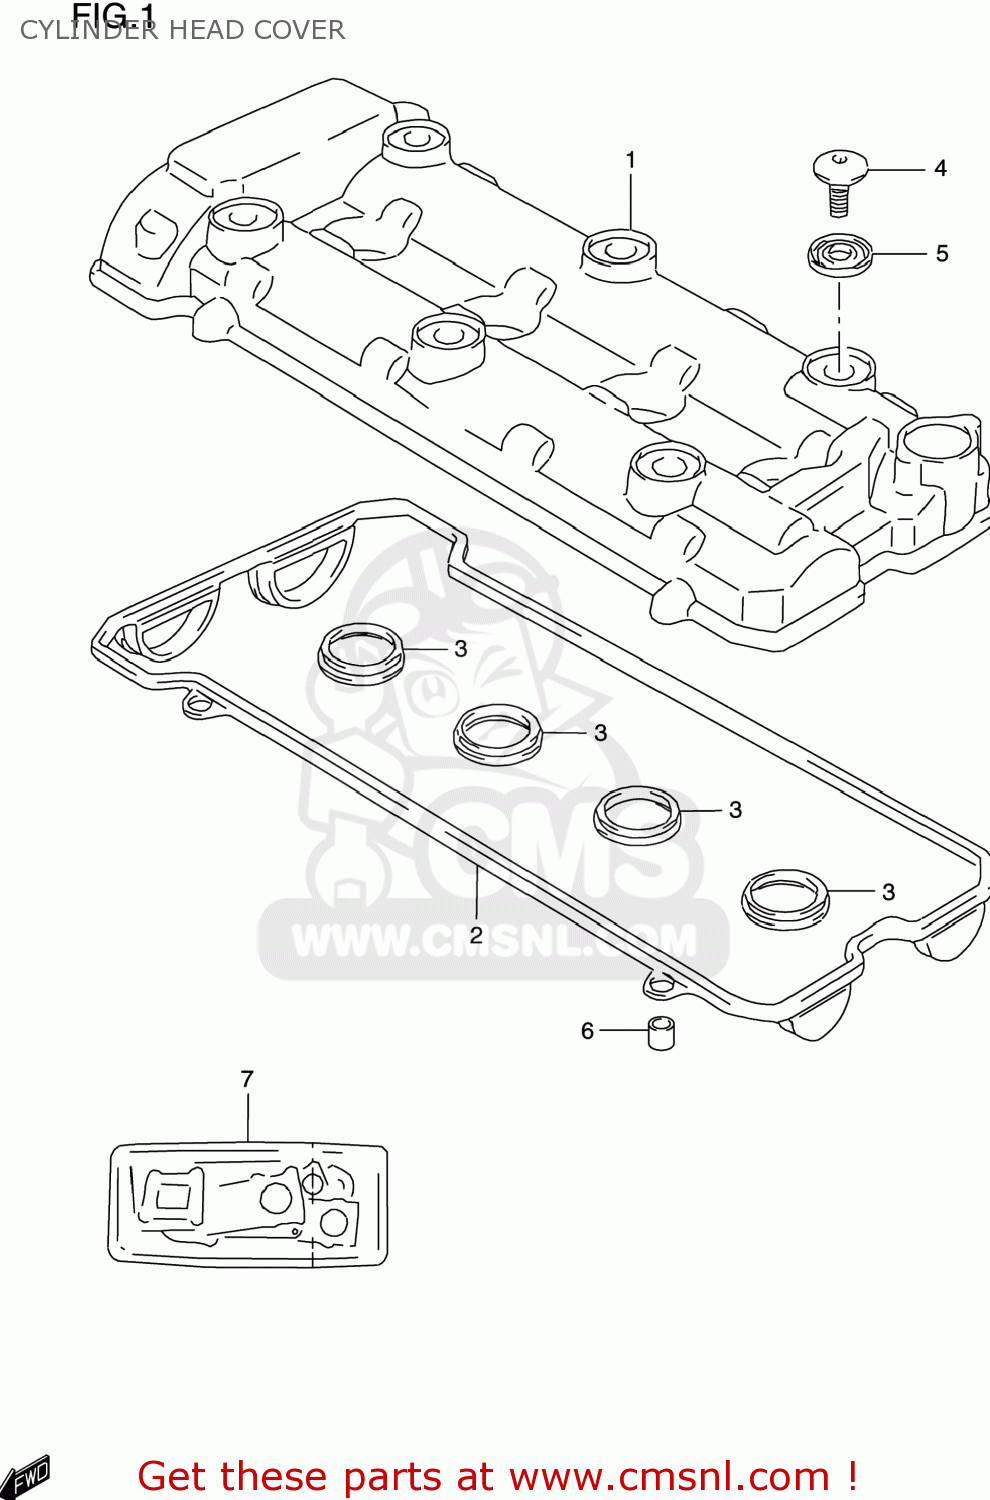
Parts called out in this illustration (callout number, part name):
1	COVER,CYLINDER HEAD
2	GASKET,CYL HEAD COVER NO.1
3	GASKET,CYL HEAD COVER NO.2
4	BOLT(7X17.5)
5	WASHER(10.6X25.5X2.3)
6	PIN(6.2X8X11)
7	GASKET SET (NAS)
